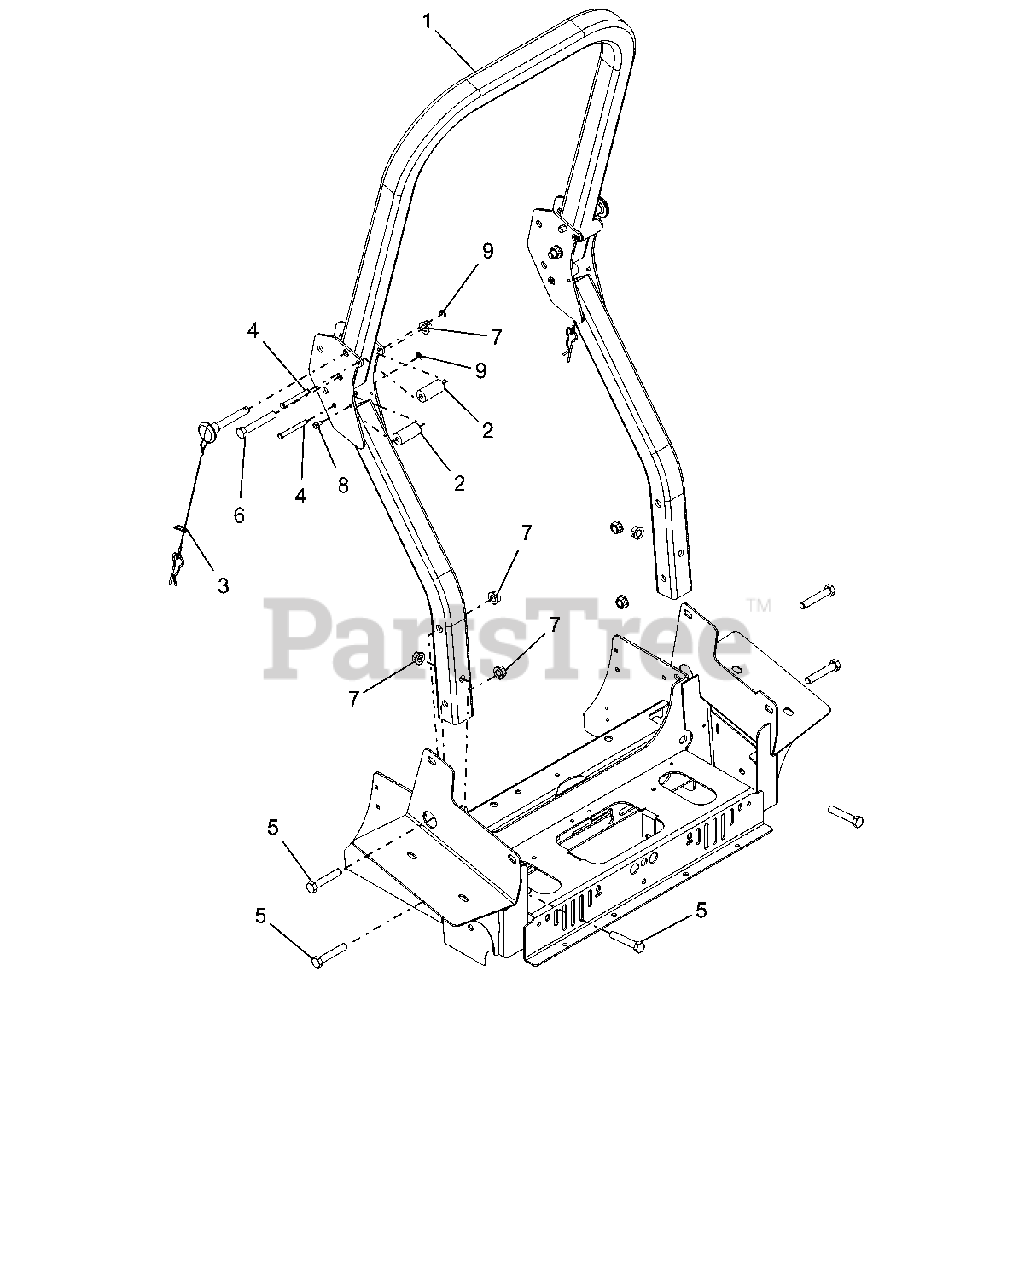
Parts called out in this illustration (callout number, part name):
1	ROPS, PT200/400 REPLACEMENT
2	BUMPER, ROPS ANTI-VIBRATION
3	PIN, ROPS W/LANYARD
4	PIN, 5/16 X 2-9/16 WITH GROOVE
5	@BLT-HEX .50-13X2.75 GR5 YWZC
6	@BLT-HEX .50-13X3.25 GR5 YWZC
7	NUT-LK-CTR-FLG .50-13 YWZC
8	SCR-TAP .25-20X.50 HWH TR YWZ
9	RING, RETAINING-E .312 X .025
